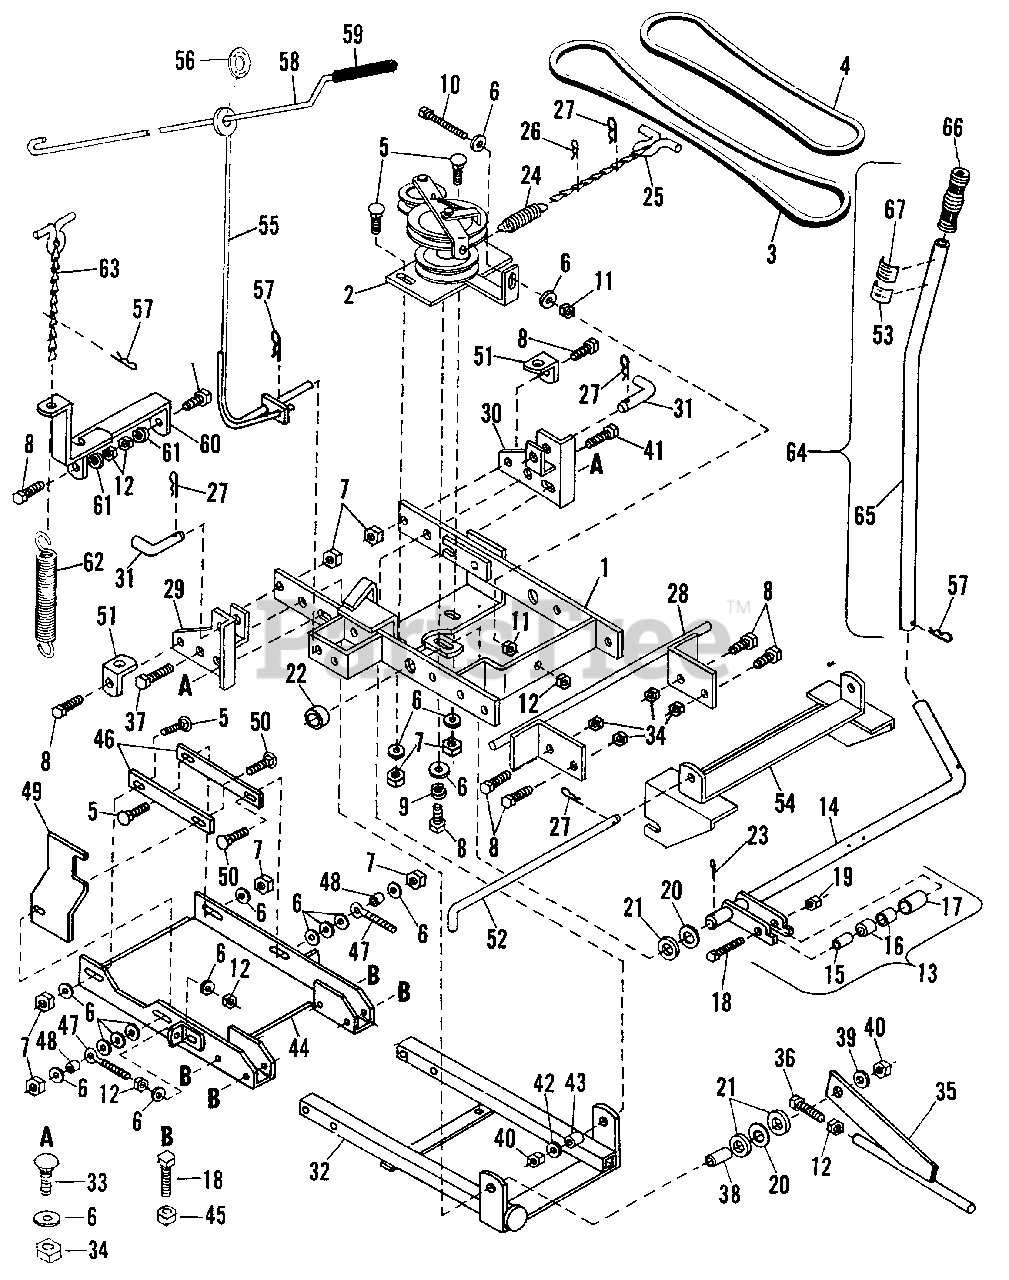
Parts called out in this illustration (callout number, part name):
1	Mounting Frame Upper Assembly
2	Pulley Mounting Bracket Assembly (Complete)
3	V-Belt - Pulley Housing to Header
4	V-Belt - Pulley Housing to Tractor
5	Bolt - 3/8-16 x 1" Carriage
6	Washer - 7/16" x 1" x .083 Flat
7	Nut & Lock Washer Assembly - 3/8-16 Hex
8	Bolt - 3/8-16 x 1" Hex Head
9	Washer - 3/8" Medium Lock
11	Nut - 3/8-16 Hex Jam
12	Nut - 3/8-16 Light Hex
13	Lift Bar Assembly (Complete)
14	Lift Bar Assembly
18	Bolt - 5/16-18 x 1-3/4" Hex Head
19	Nut & Lock Washer Assembly - 5/16-18 Hex
21	Washer - 13/16" x 1 1/2" x .134 Flat
23	Pin - 1/8" x 1 1/4" Cotter
25	Chain & Toggle Assembly
26	Spring Clip
27	Hair Cotter Pin
28	Rear Mounting Bracket Assembly
29	Front Mounting Bracket (Left Hand) Assembly
30	Front Mounting Bracket (Right Hand) Assembly
31	Locating Pin
32	Mounting Frame Lower Assembly
33	Bolt - 3/8-16 x 1 1/4" Carriage
34	Nut - 3/8-16 Hex Lock
35	Lift Extension Assembly
37	Bolt - 1/2-13 x 2 1/4" Hex Head
39	Washer - 1/2" x 1 1/4" x .083 Flat
40	Nut - 1/2-13 Hex Lock
41	Bolt - 1/2-13 x 1-3/4" Hex Head
42	Washer - 17/32" x 1-1/16" x .095 Flat
44	Pivot Bracket Channel Assembly
45	Nut - 5/16-18 Hex Lock
46	Header Channel Strap
49	Belt Adjustment Guide Bracket
50	Bolt - 3/8-16 x 2 1/4" Carriage
51	Chain Anchor Bracket
52	Locating Pin
53	Lift Control Decal
54	Rear Hanger Assembly
55	Crank Rod Support & Decal Assembly
56	Chute Direction Decal
57	Hair Cotter Pin
58	Crank Rod
59	Handle Grip
60	Chain Anchor Assembly
61	Washer - 3/8" Medium Lock
62	Lift Spring
63	Chain & Toggle Assembly
64	Lift Handle Assembly (Complete)
65	Lift Handle
66	Handle Grip
67	Raise & Lower Decal
NP	Repair Parts Manual
NP	Operator's Manual
